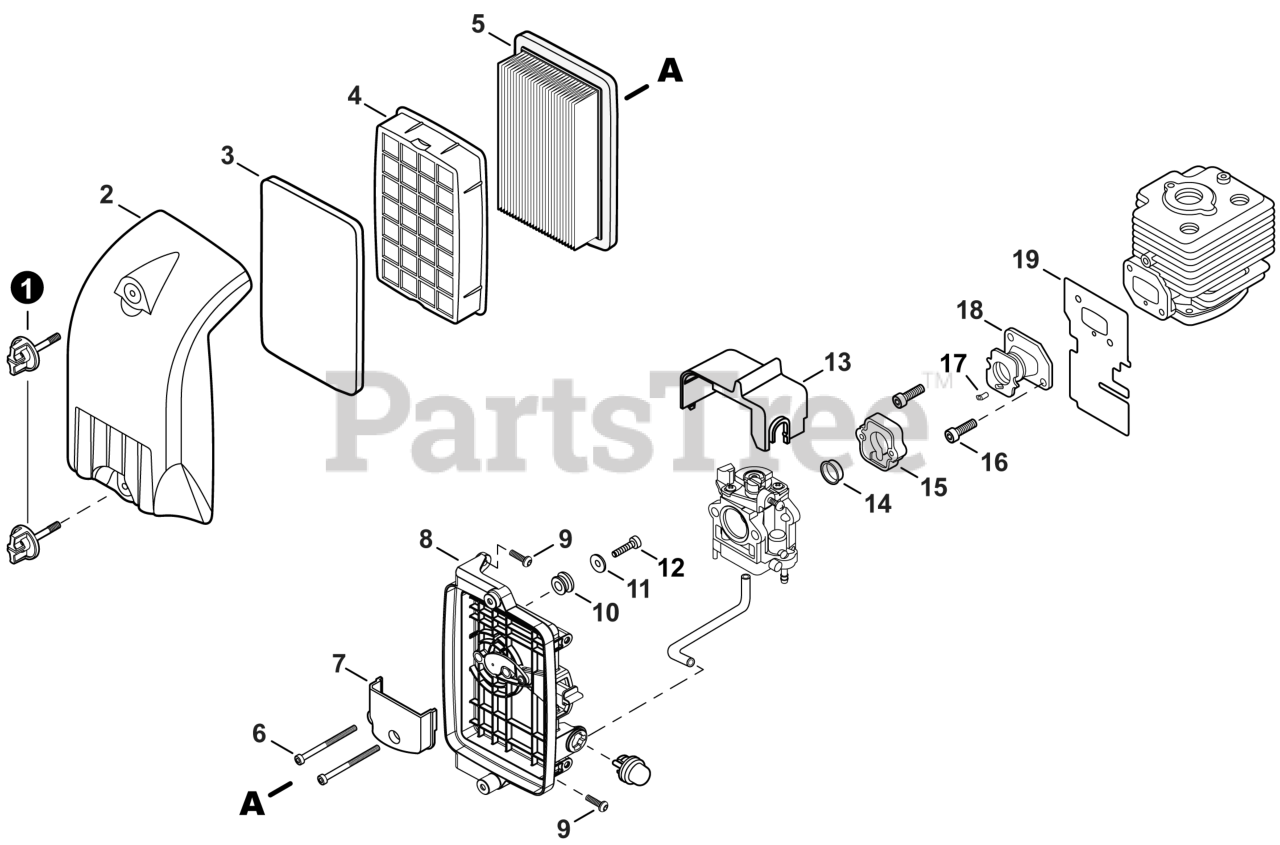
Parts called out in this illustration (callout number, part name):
1	THUMBSCREW
2	COVER, AIR FILTER
3	PRE-FILTER, FOAM
4	RETAINER, PRE-FILTER
5	FILTER, AIR
6	BOLT, TORX 5×55
7	PLATE, PREVENT
8	CASE, AIR FILTER
9	BOLT, TORX 5×20
10	GUIDE, CABLE
11	WASHER 5.5×16×0.8
12	BOLT, TORX 5×16
13	CAP, CARBURETOR
14	RING, SEAL
15	ADAPTOR, INTAKE
16	SCREW 5×12
17	COLLAR 3
18	BELLOWS, INTAKE
19	HEAT SHIELD, INTAKE
